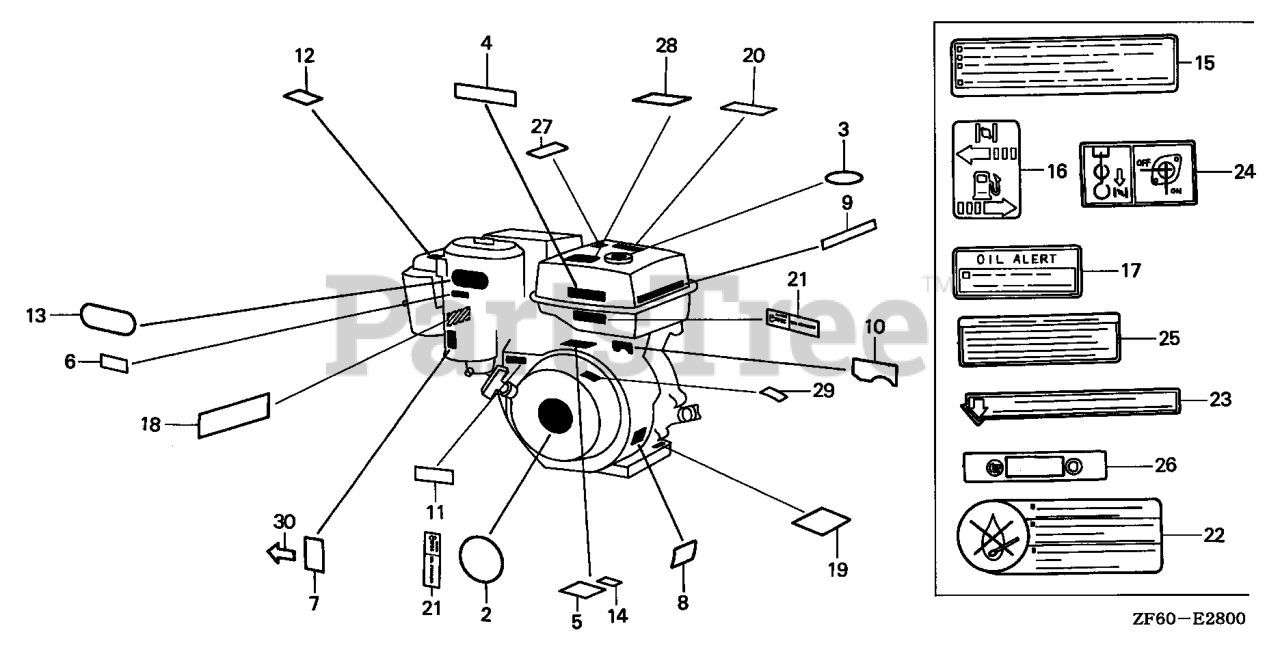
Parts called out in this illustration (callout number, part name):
2	EMBLEM (13. (HONDA)
4	MARK, CAUTION (PICTOGRAPH)
4	LABEL, CAUTION (ENGLISH, ETC.)
7	MARK, CHOKE (EXTERNAL)
7	MARK, CHOKE (BLACK)
9	MARK, OIL ALERT (ENGLISH)
11	MARK, THROTTLE INDICATION
12	LABEL, AIR CLEANER CAUTION
13	MARK, AIR CLEANER SALES POINT
